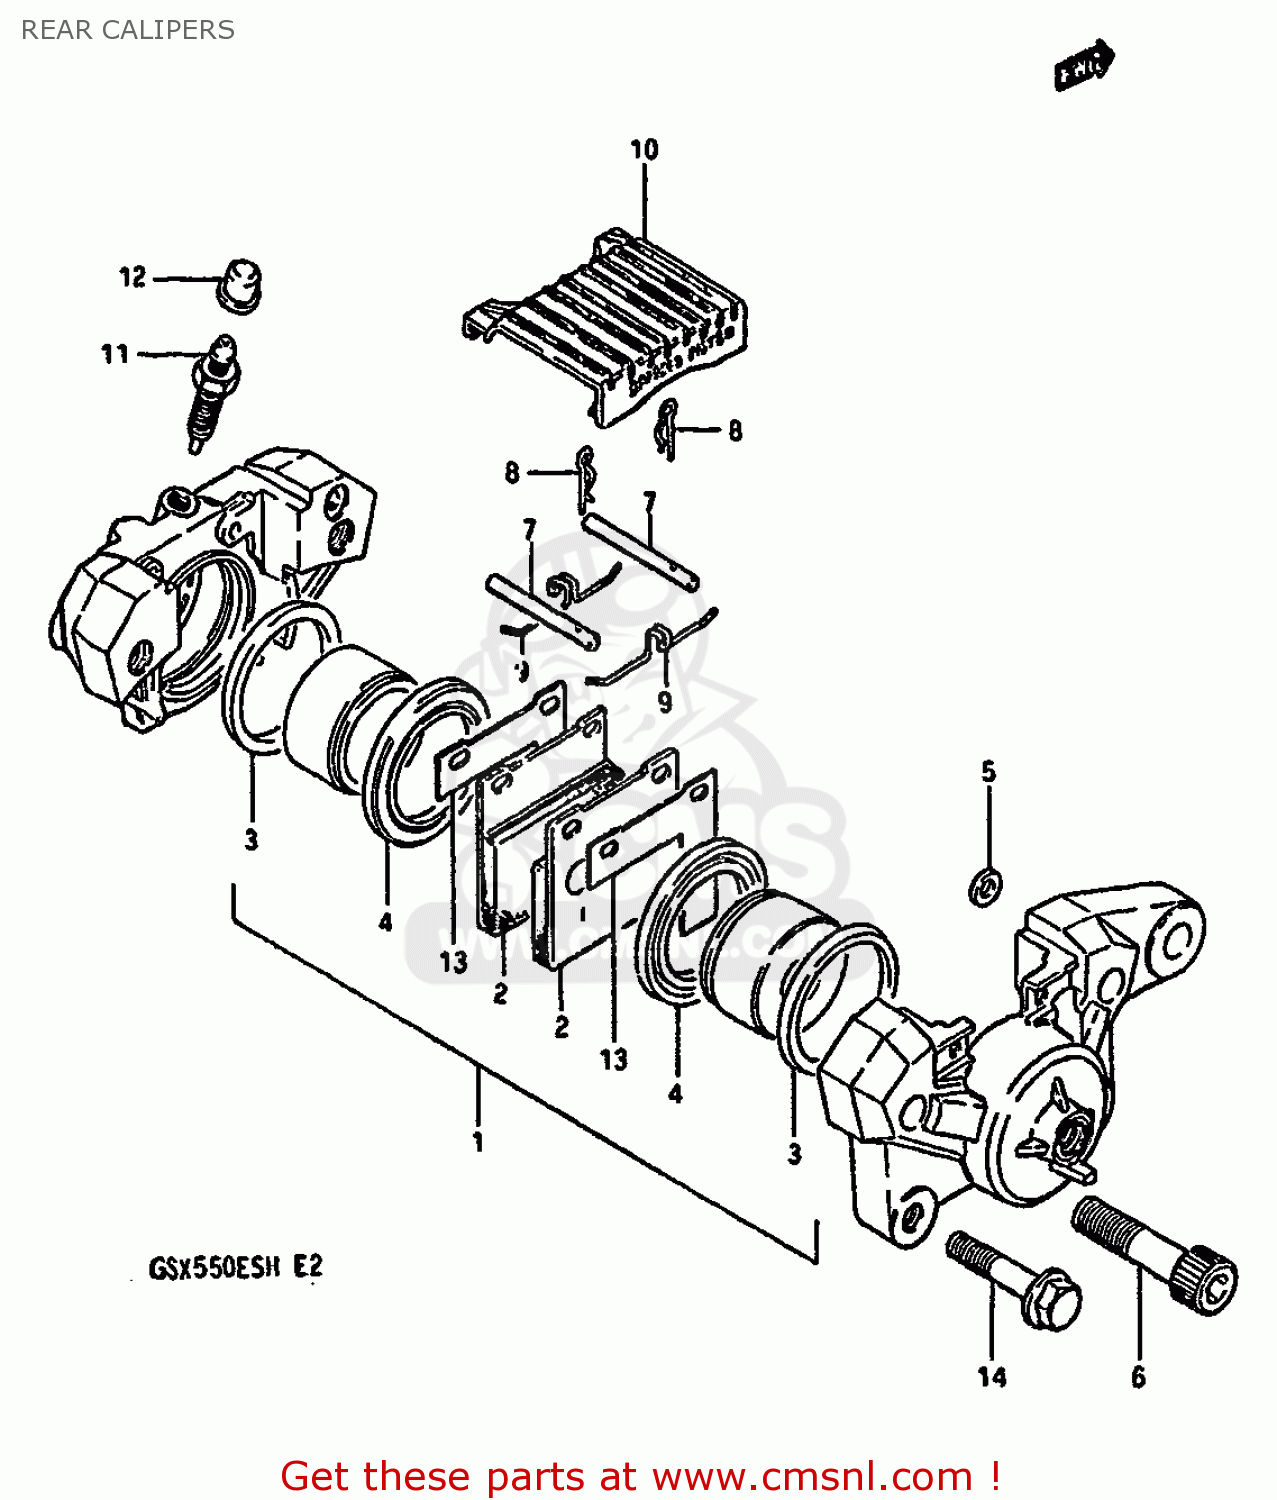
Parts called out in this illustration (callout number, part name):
1	PISTON SET
2	PAD
3	SEAL,PISTON
4	BOOT
5	SEAL,JOINT
6	BOLT,CALIPER HOUSING
7	PIN,PAD
8	CLIP,PAD PIN
9	SPRING
10	COVER
11	BLEEDER
12	CAP,BREATHER
13	SHIM
14	BOLT
